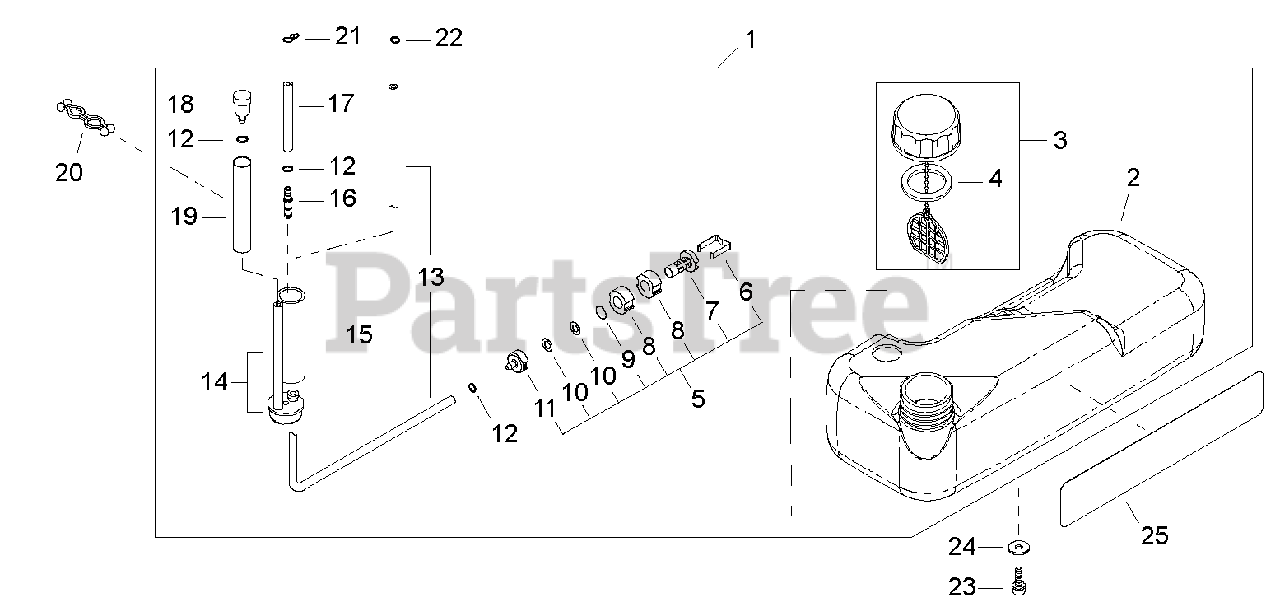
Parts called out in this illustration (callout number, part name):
1	FUEL TANK ASSY
2	TANK, FUEL
3	CAP ASSY
4	GASKET, CAP
5	FILTER, FUEL
6	CLIP, FILTER
7	CASE, FILTER
8	FILTER, FUEL
9	RING, RETAINING
10	SCREEN, FILTER
11	WEIGHT, FUEL FILTER
12	RING, RETAINING - 6
13	PIPE - FUEL
14	VENT PIPE ASSY
15	SLEEVE
16	CONNECTOR, PIPE
17	PIPE - RETURN
18	VENT, FUEL TANK
19	TUBE
20	CLIP
21	CLIP - SPRING
22	RING, RETAINING - 6
23	SCREW - 5X14
24	COLLAR
25	LABEL - MODEL EB8520
